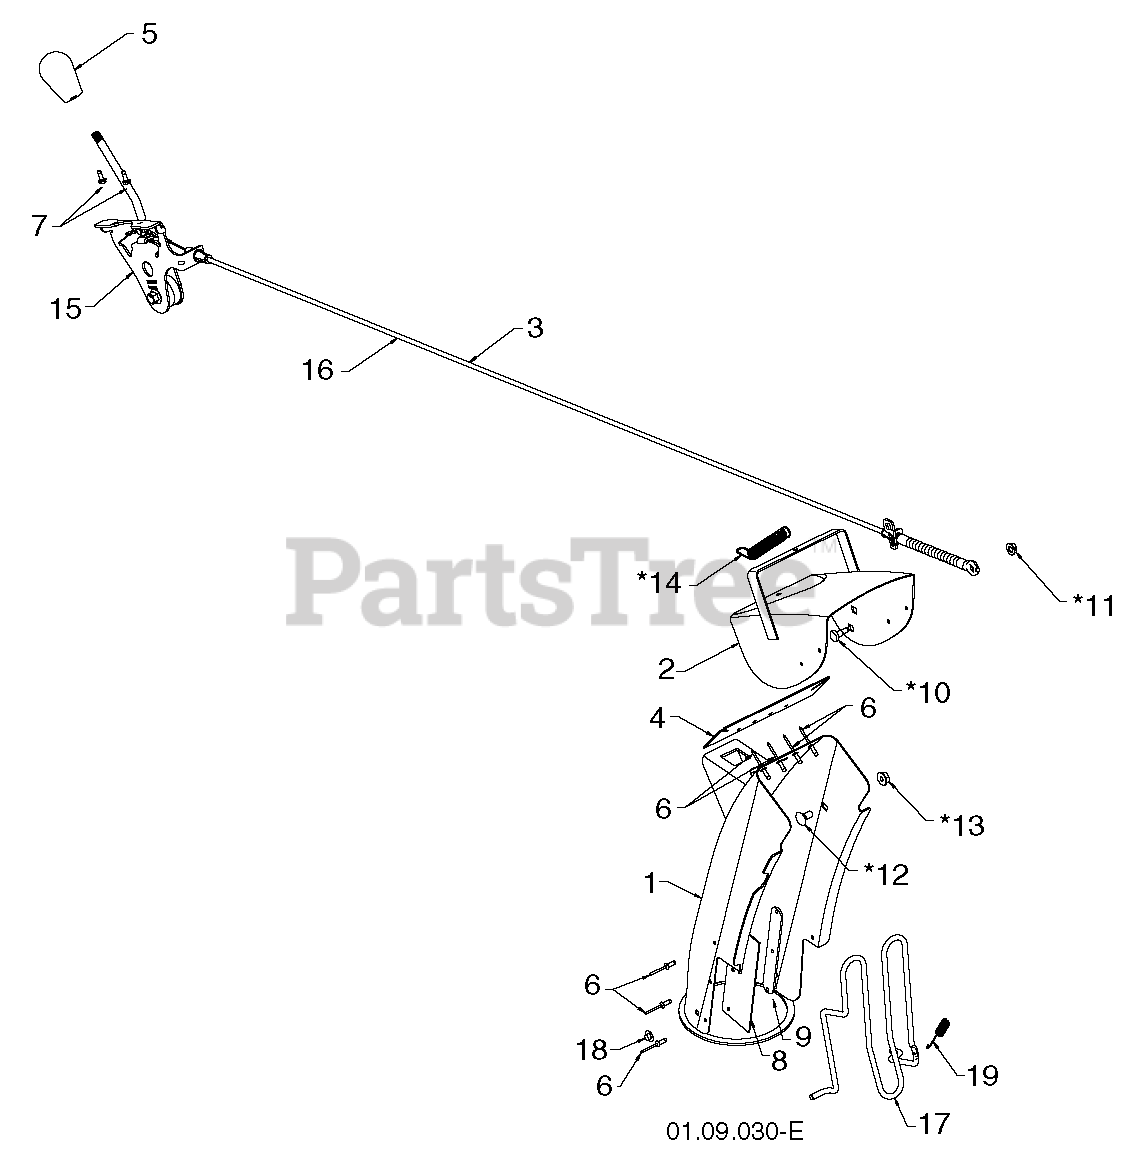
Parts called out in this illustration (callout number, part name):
1	RP_CHUTE.WELDMENT.SNOW.ORANGE
2	DEFLECTOR.WELDMENT.PNT.ORANGE
3	CONTROL.ASM.DEFLEC.BLK.BOWDEN
4	SEAL.DEFLECTOR
5	KNOB.OVERMOLD.DS.HUSQVARNA/BLK
6	RIVET BLIND
8	SHIELD.SNOW.CHUTE
9	STRAP.SHEILD.RETAINER
10	BOLT, SHOULDER
11	NUT.HEX.FLANGE.1/4
12	BOLT CAR BLK 5/16-18 X 5/8
13	NUT.LOCK.5/16-18
14	SPRING.DEFLECTOR.REM.CHUTE
15	RP CNTRL.HEAD.ASSEM.DEFLECTOR
16	RP CABLE.DEFLECTOR.BOWDEN
17	ROD.GUARD.CHUTE (2 2)
18	NUT
19	SPRING.CHUTE.GUARD
